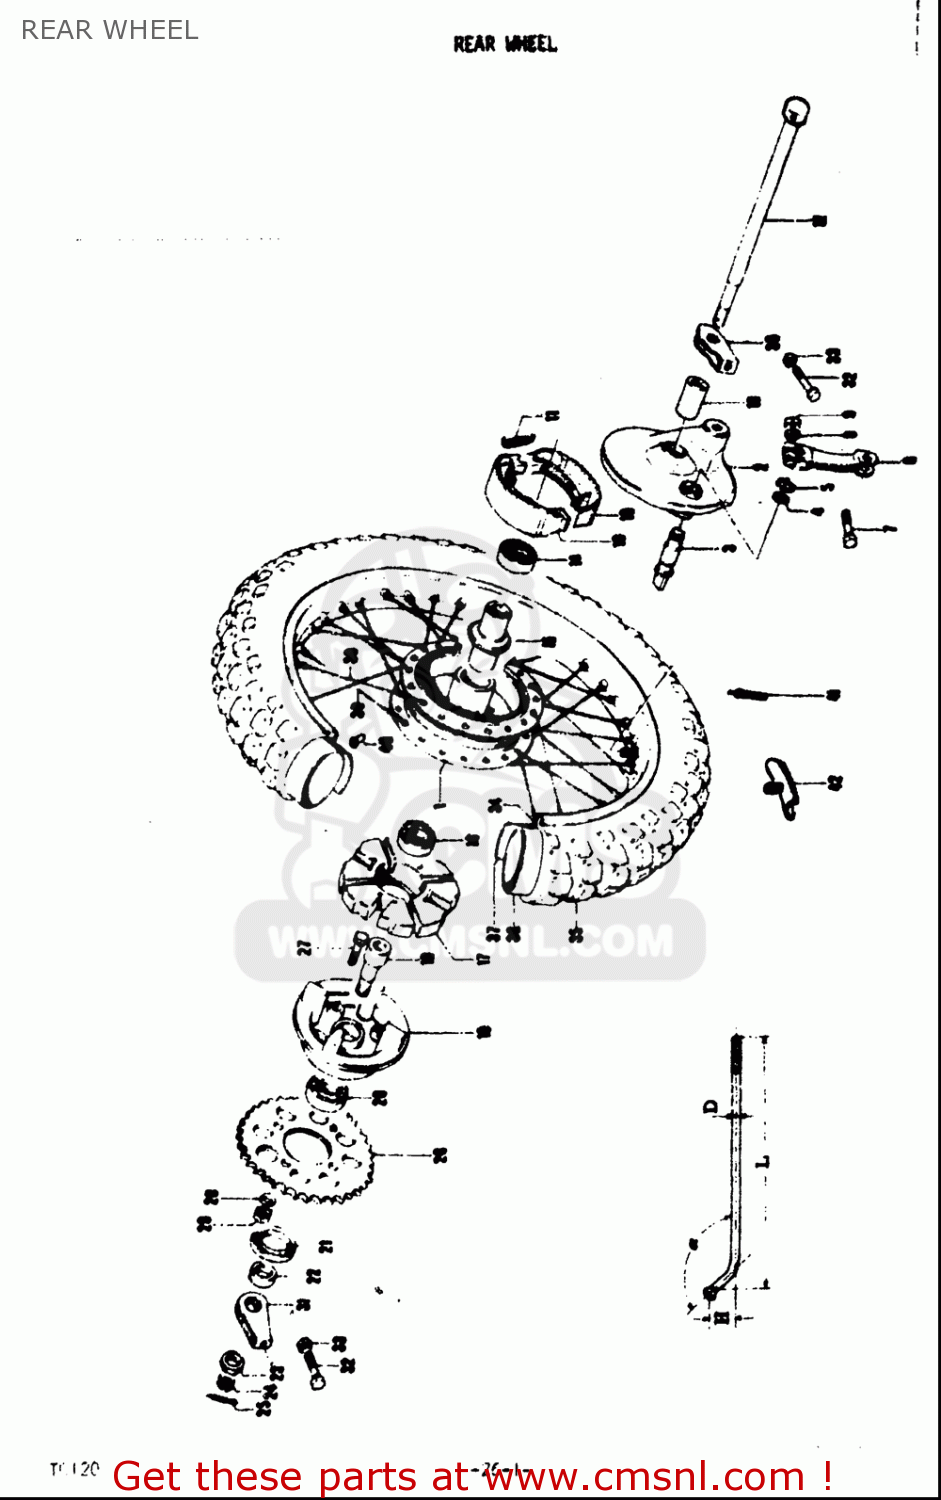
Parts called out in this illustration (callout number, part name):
4	O RING(D:2.5,ID:11.4)
5	WASHER(12.5X20X1)
6	LEVER,RR BRAKE CAM
7	BOLT(6X31)
8	WASHER
9	NUT
11	SPRING(L:35.8)
12	AXLE,RR
13	SPACER(15.2X26X33)
16	BEARING
17	ABSORBER ASSY,HUB SHOCK
18	SHAFT,RR SPROCKET DRUM
20	BEARING(20X47X14)
21	SEAL,OIL(28X47X7)
22	SPACER(20X28X13)
23	NUT
24	NUT 12MM
25	PIN
26	SPROCKET,RR(NT:41)
27	BOLT(8X33.5)
28	WASHER,LOCK
29	NUT
32	BOLT(6X38)
33	NUT
34	RIM,FR WHEEL 1.60X18
36	TUBE ASSY,WHEEL INNER
37	SPOKE SET,RR
